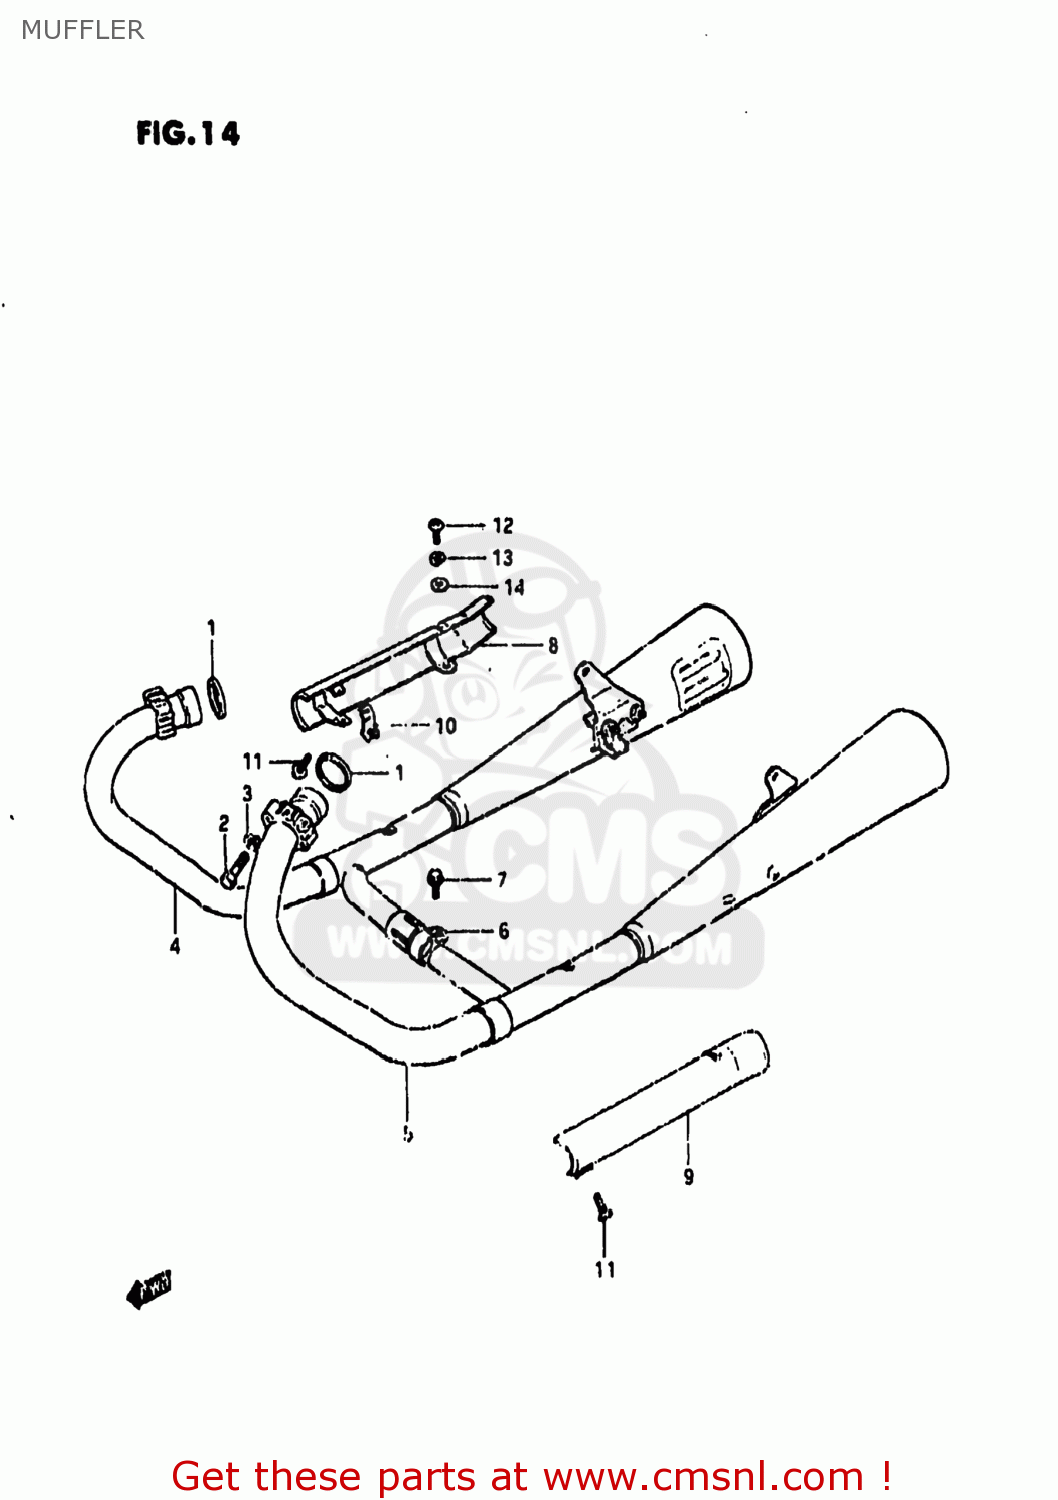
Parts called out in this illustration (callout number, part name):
1	GASKET,EXHAUST PIPE (NAS)
2	BOLT 8X40
3	LOCK WASHER
4	MUFFLER ASSEMBLY,RIGHT
5	MUFFLER ASSEMBLY
6	CLAMP
7	BOLT
8	COVER,MUFFLER,RIGHT
9	COVER,MUFFLER
10	CLAMP,MUFFLER COVER
11	SCREW
12	SCREW
13	LOCK WASHER
14	WASHER
